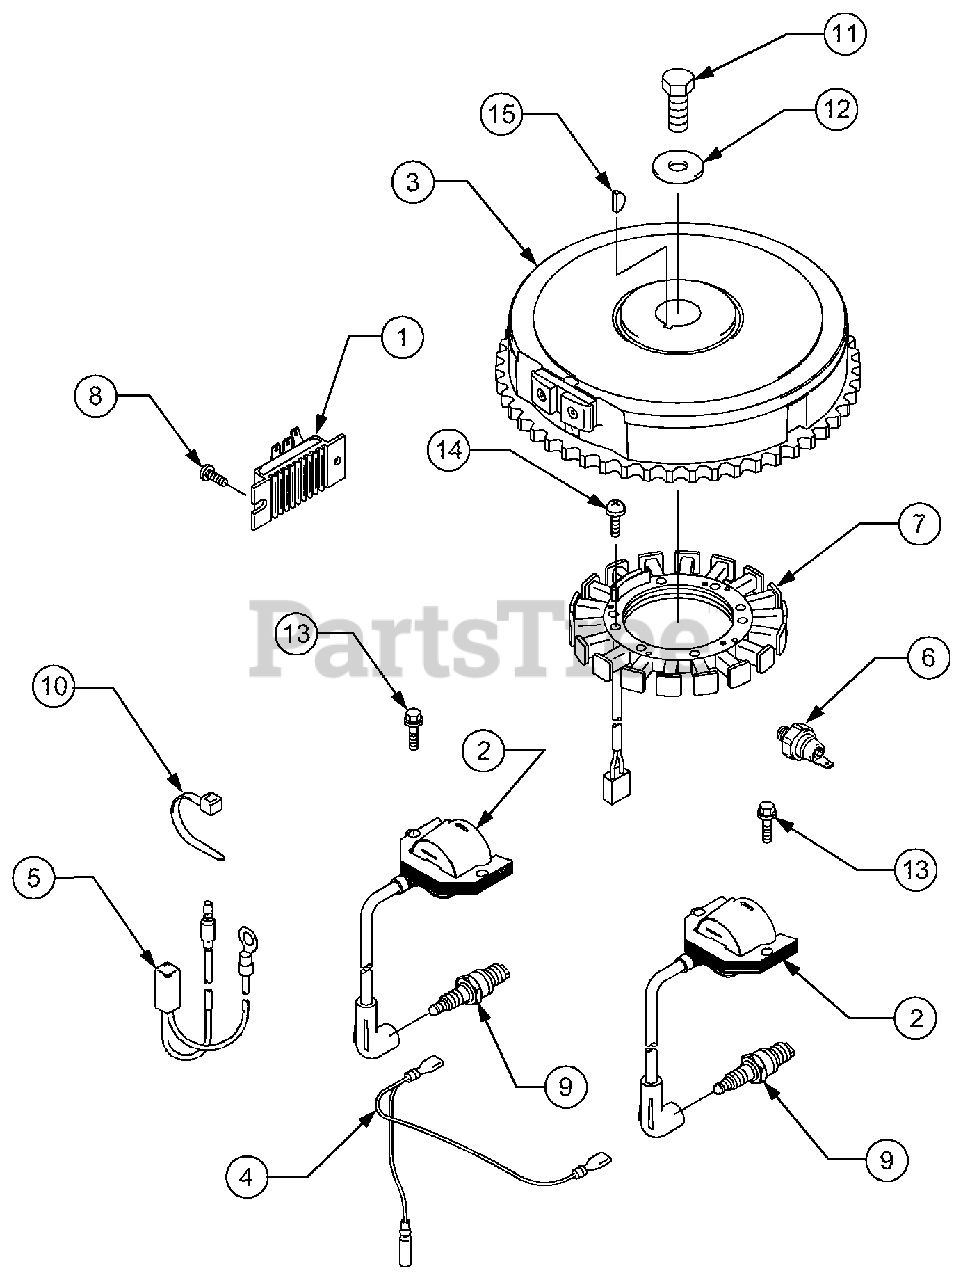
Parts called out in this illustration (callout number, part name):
1	Regulator, Voltage
2	Coil Assy, Ignition
3	Flywheel Assy
6	Switch, Oil Pressure
7	Coil, Charging
9	Plug, Spark - RCJ8Y
11	Bolt, 12x30
13	Bolt, Flanged
14	Screw, Pan Hd. Cross
15	Key, Woodruff
